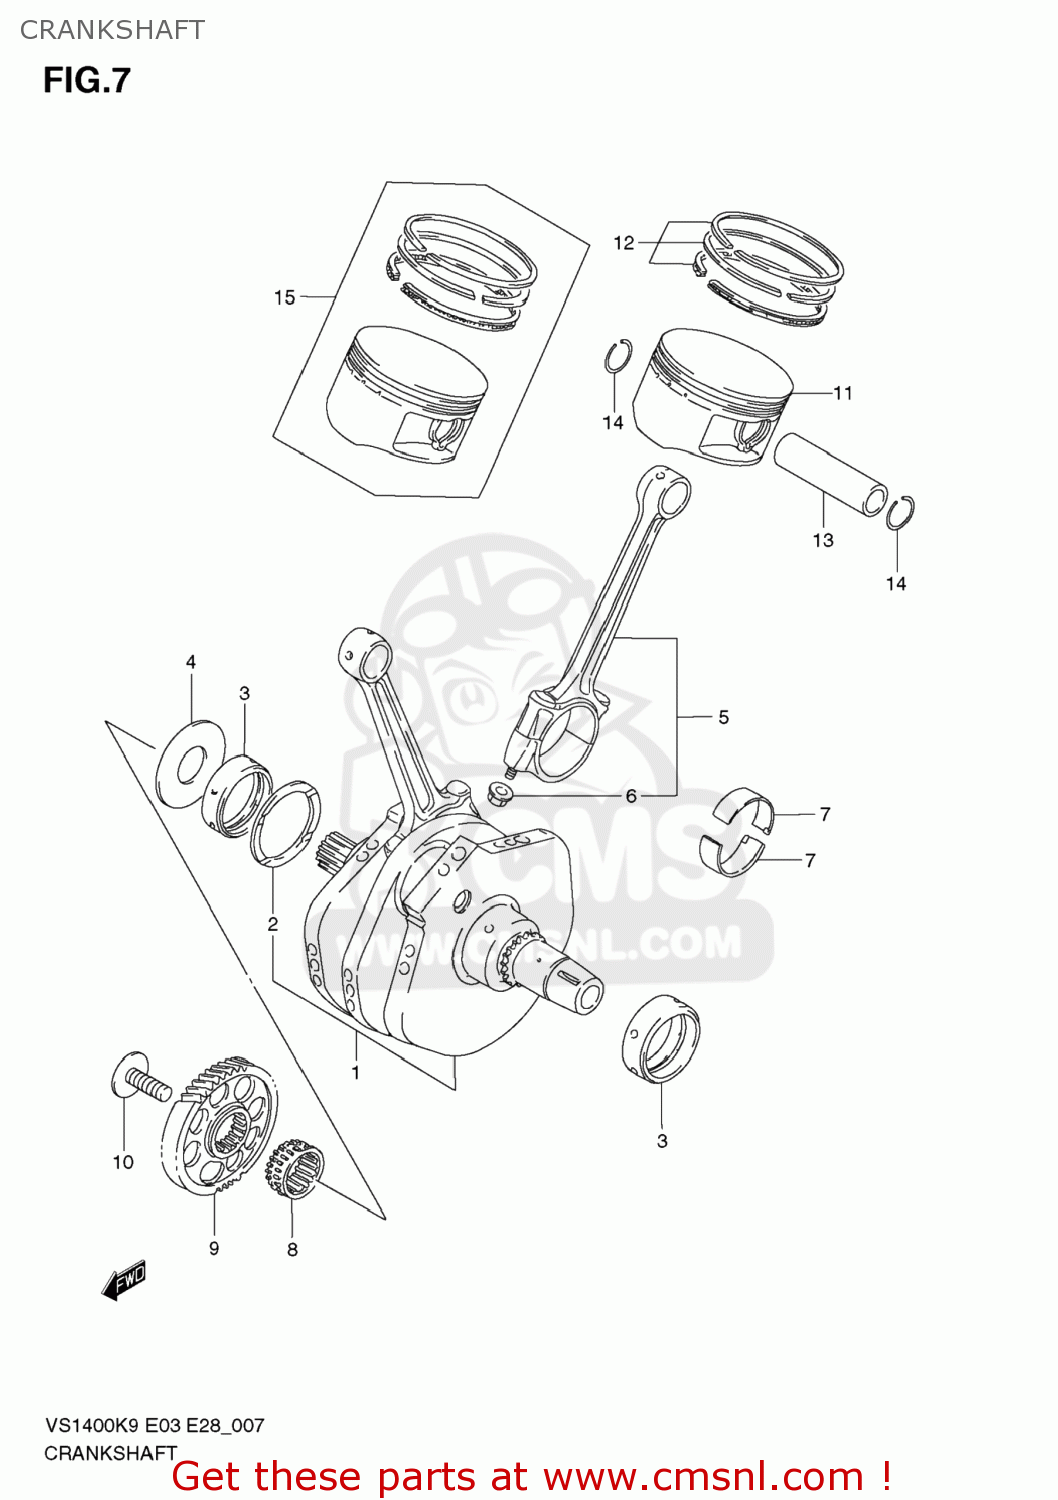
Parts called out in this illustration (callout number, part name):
1	CRANKSHAFT SET
2	PLATE,CRANK THRUST
3	METAL,CRANKSHAFT
4	WASHER,CRANK THRUST
5	CONNECTING ROD ASSY
6	NUT
7	METAL,CRANK PIN
8	SPROCKET,CAM CHAIN DRIVE,R
9	GEAR,PRIMARY DRIVE
10	BOLT(14X28)
11	PISTON
12	RING SET,PISTON
13	PIN,PISTON
14	CIRCLIP
15	PISTON SET(OS:0.5)
